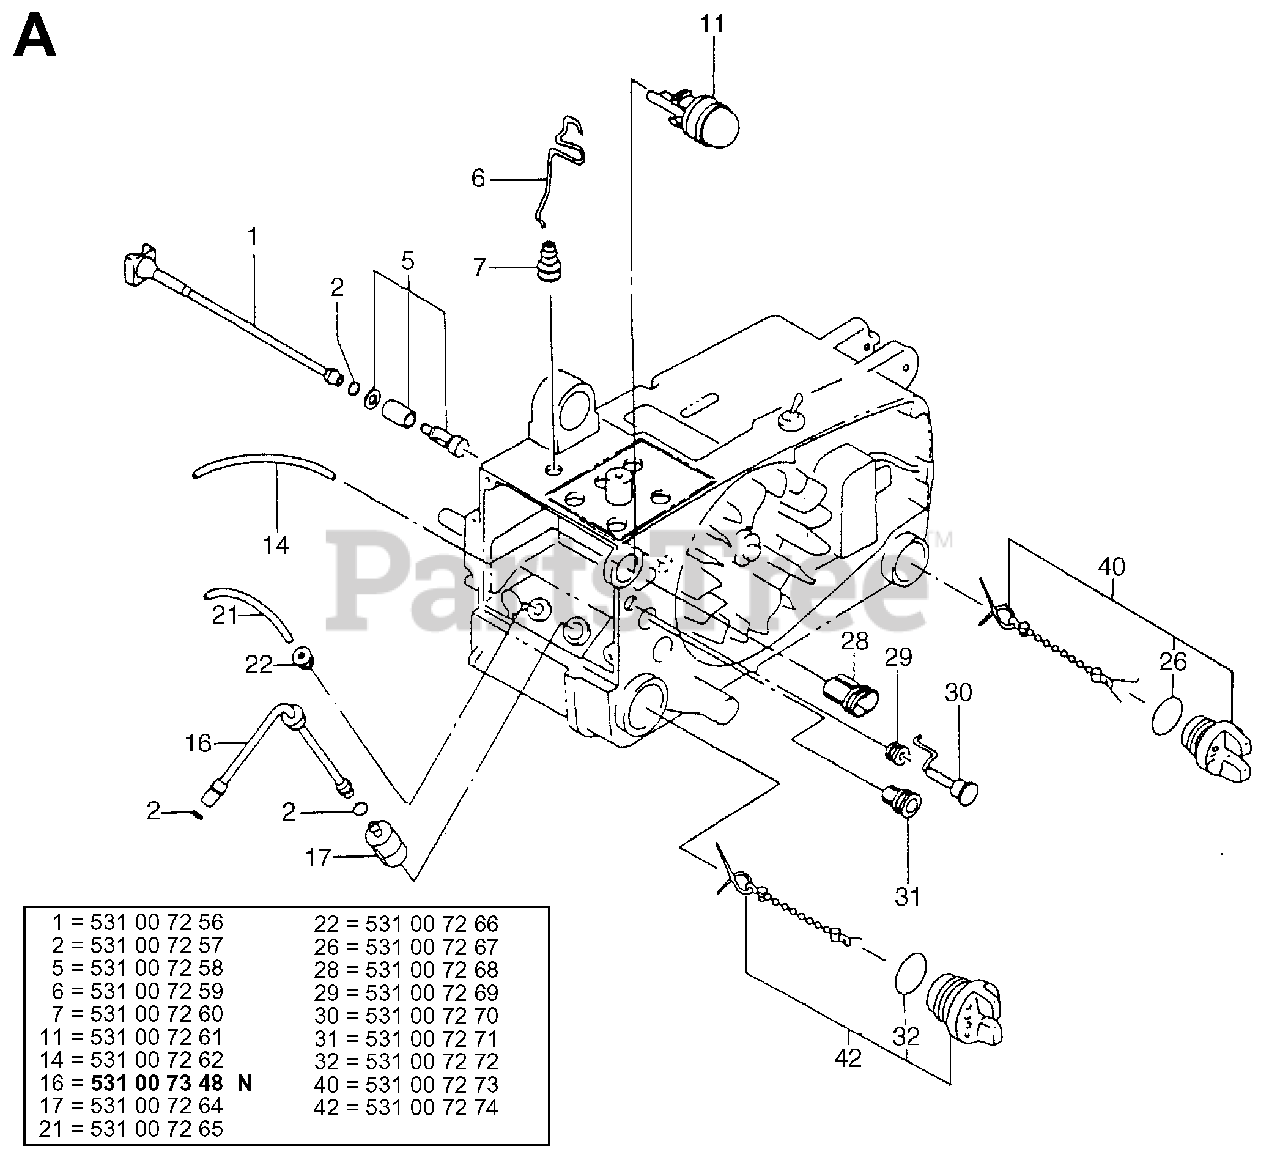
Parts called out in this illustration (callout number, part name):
6	THROTTLE WIRE
16	PIPE
30	CHOKE CONTROL
